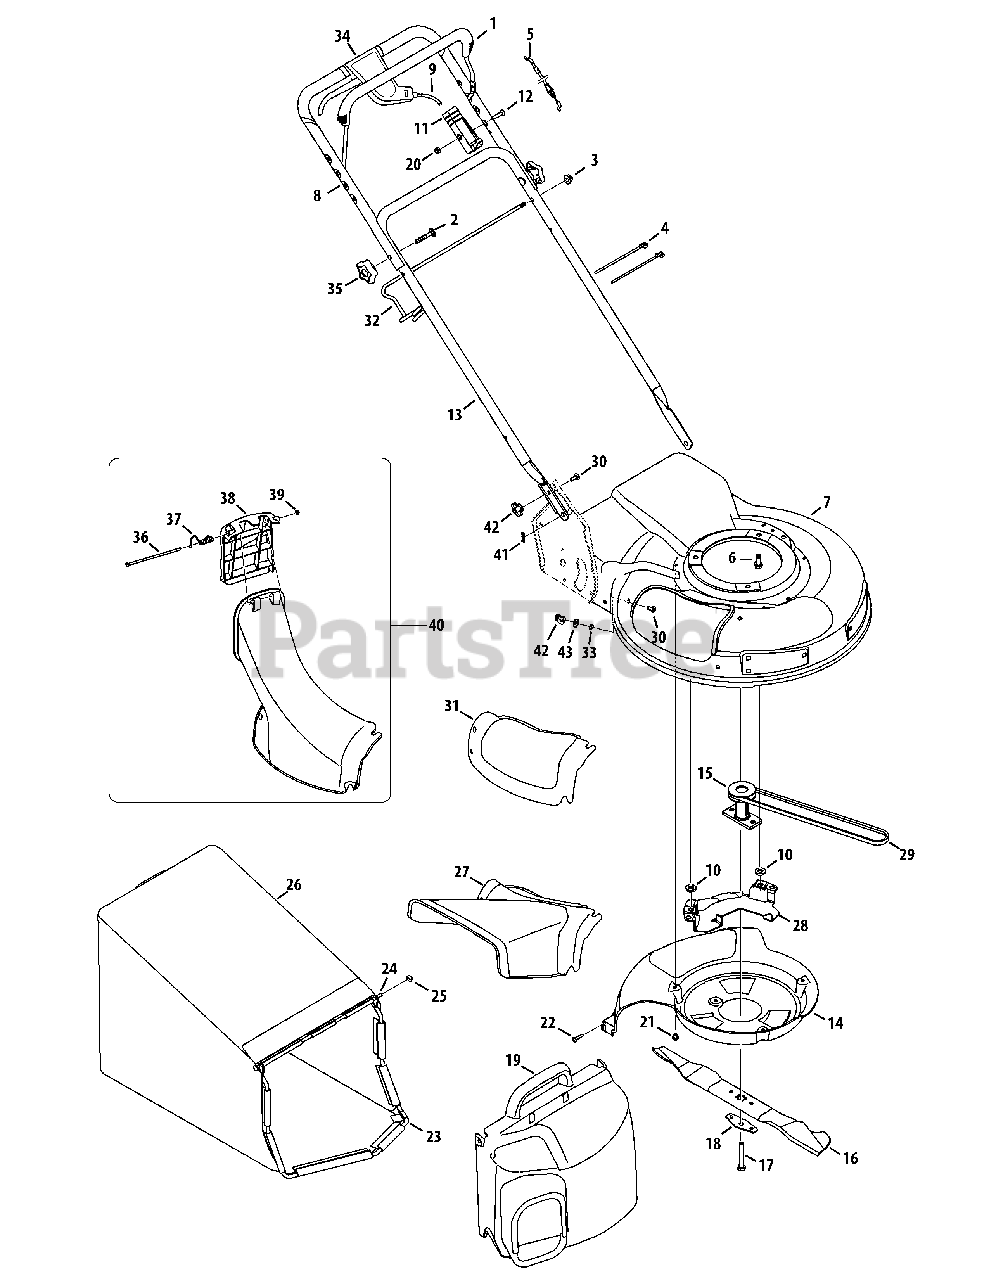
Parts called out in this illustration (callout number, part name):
1	Blade Control
2	Carriage Bolt 5/16-18 x 2
3	Flange Lock Nut, 5/16-18
4	Cable Tie
5	Control Cable
6	TT Screw, 3/8-16 x 1.00
9	Drive Cable
10	Washer, Flat, .407 x .812 x .135
11	Control Cable Mount
12	Screw, 1/4-20 x 1.310
14	Engine Baffle
15	Blade Adapter
16	21-inch Mulching Blade
17	HH Cap Screw, 3/8-24 x 2.50
18	Bell Blade Spacer
19	Grass Bag Cover Assembly
20	Hex Lock Nut 1/4-20
21	TT Screw 1/4-20 x .375
22	HL Screw 1/4-15 x .75
23	Grass Bag Frame
24	Grass Bag Pivot Rod
25	Cap Speed Nut
26	Grass Bag
27	Side Discharge Chute
28	Belt Keeper
30	Carriage Screw 1/4-20 x .75
31	Mulch Cover
32	Grass Bag Support Rod
34	Drive Control Assembly
36	Chute Door Pivot Rod
37	Torsion Spring
38	Top Discharge Door Chute
40	Top Discharge Chute Assembly
41	Cotter Pin
43	Flat Washer, .260 x .720 x .060
